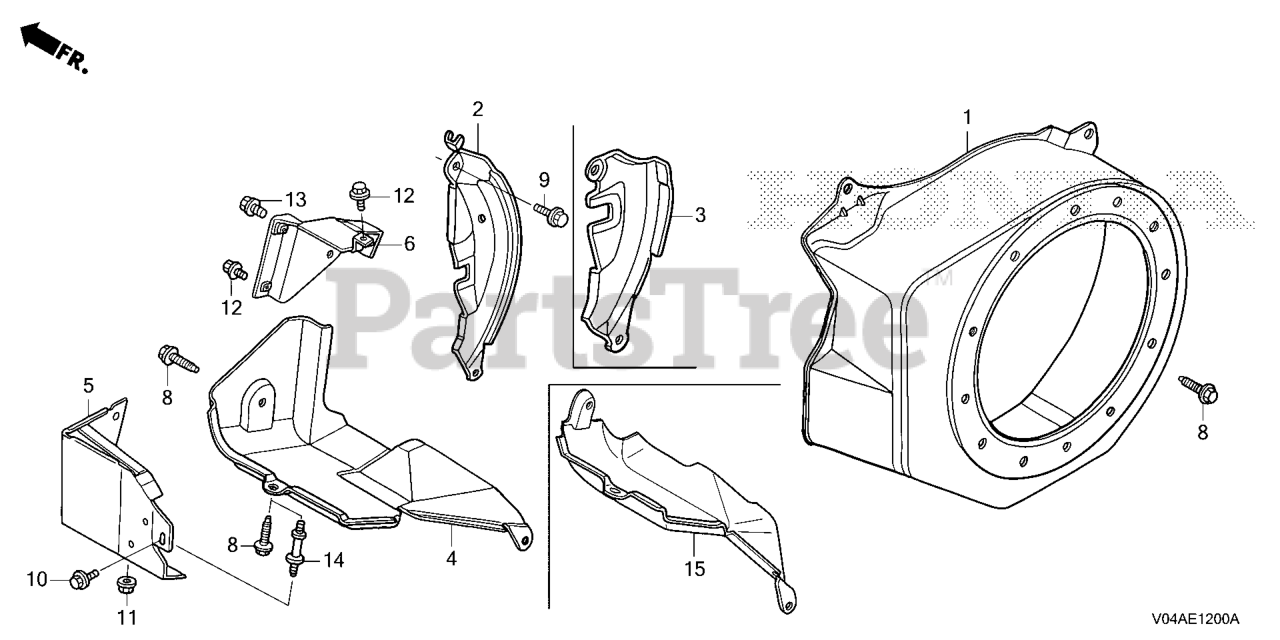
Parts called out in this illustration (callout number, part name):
1	COVER, FAN *R280* (POWER RED)
3	PLATE, SIDE (STARTER MOTOR)
8	BOLT, FLANGE (6X12) (CT200)
9	BOLT, FLANGE (6X25) Use up to Engine SN 2056819.
